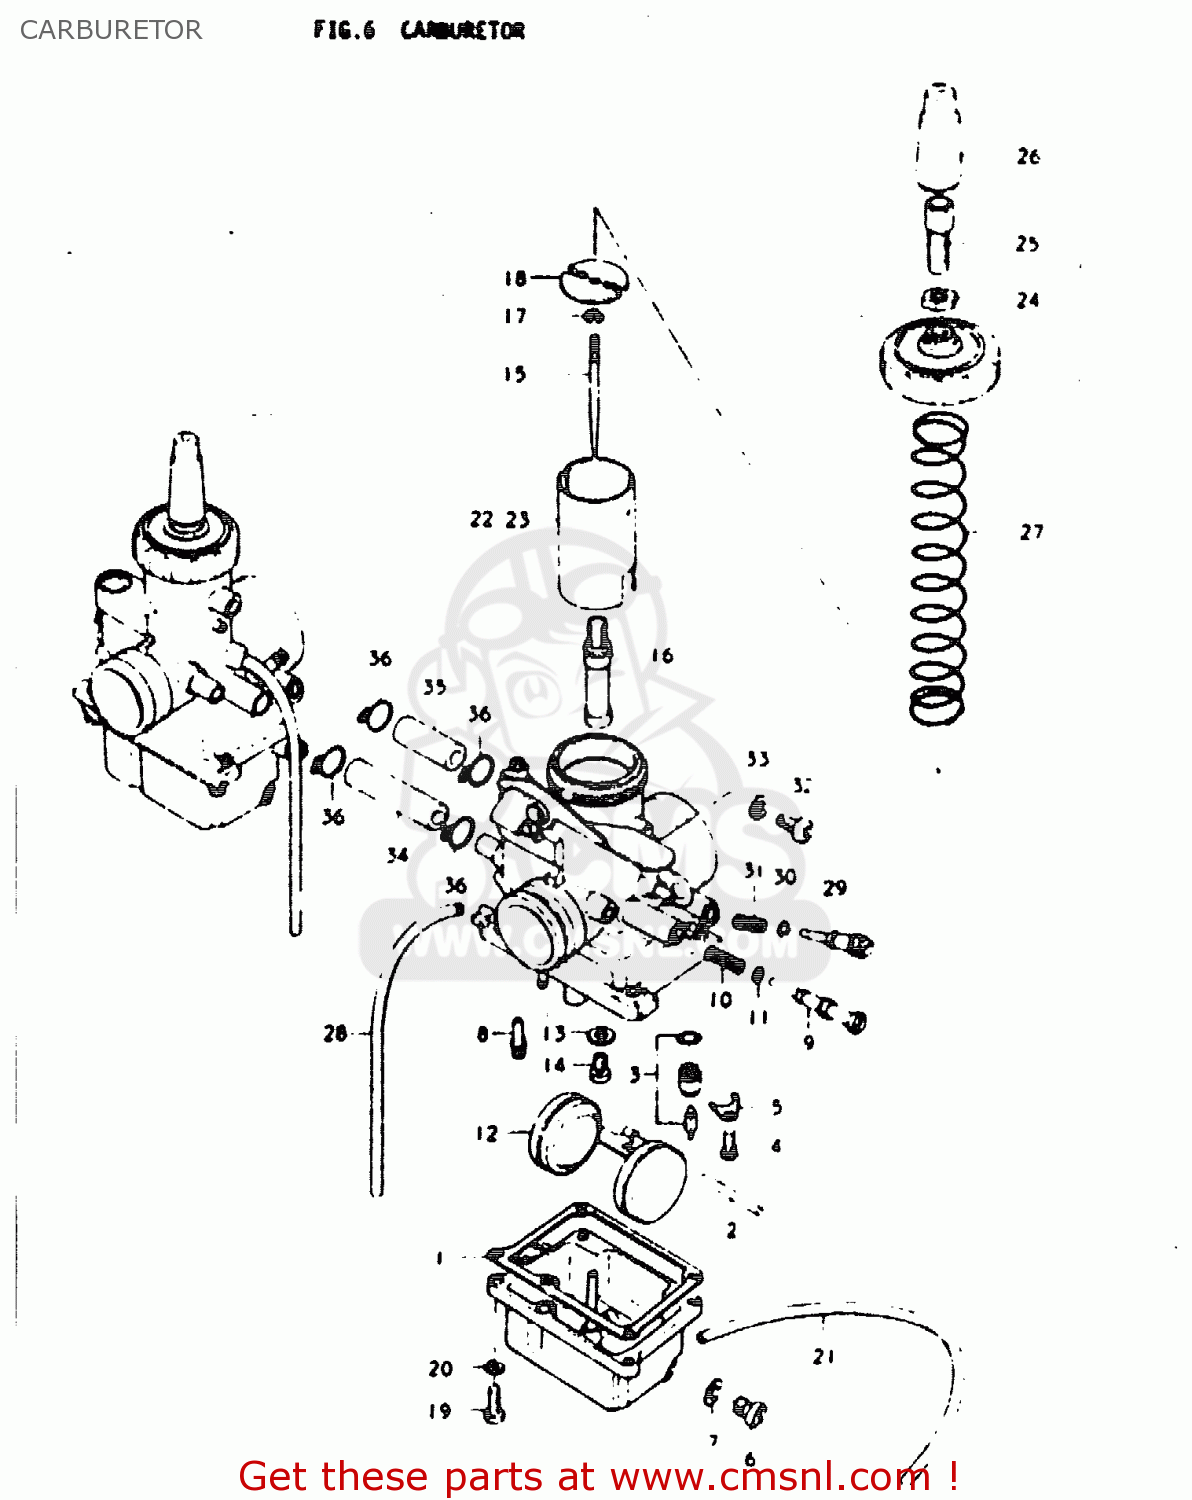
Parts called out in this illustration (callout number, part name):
1	GASKET,FLOAT CAHMBER (NAS)
2	PIN,FLOAT
3	VALVE ASSY,NEEDLE
4	SCREW
5	PLATE,NEEDLE VALVE FITING
6	PLUG
7	GASKET,DRAIN,PLUG (NAS)
8	JET
9	SCREW,THROTTLE STOP
10	SPRING
11	O-RING
12	FLOAT
13	WASHER
14	JET
15	NEEDLE, JET
16	JET, NEEDLE
17	CLIP
18	PLATE, SPRING
19	SCREW
20	LOCK WASHER
21	HOSE
22	VALVE, THROTTLE LH
23	VALVE, THROTTLE RH
24	NUT
25	ADJUSTER,CABLE
26	BOOT
27	SPRING,THROTTLE VALVE
28	HOSE
29	SCREW,PILOT AIR
30	O RING
31	SPRING
32	SCREW
33	GASKET,DRAIN PLUG (NAS)
34	HOSE
35	HOSE
36	CLIP
